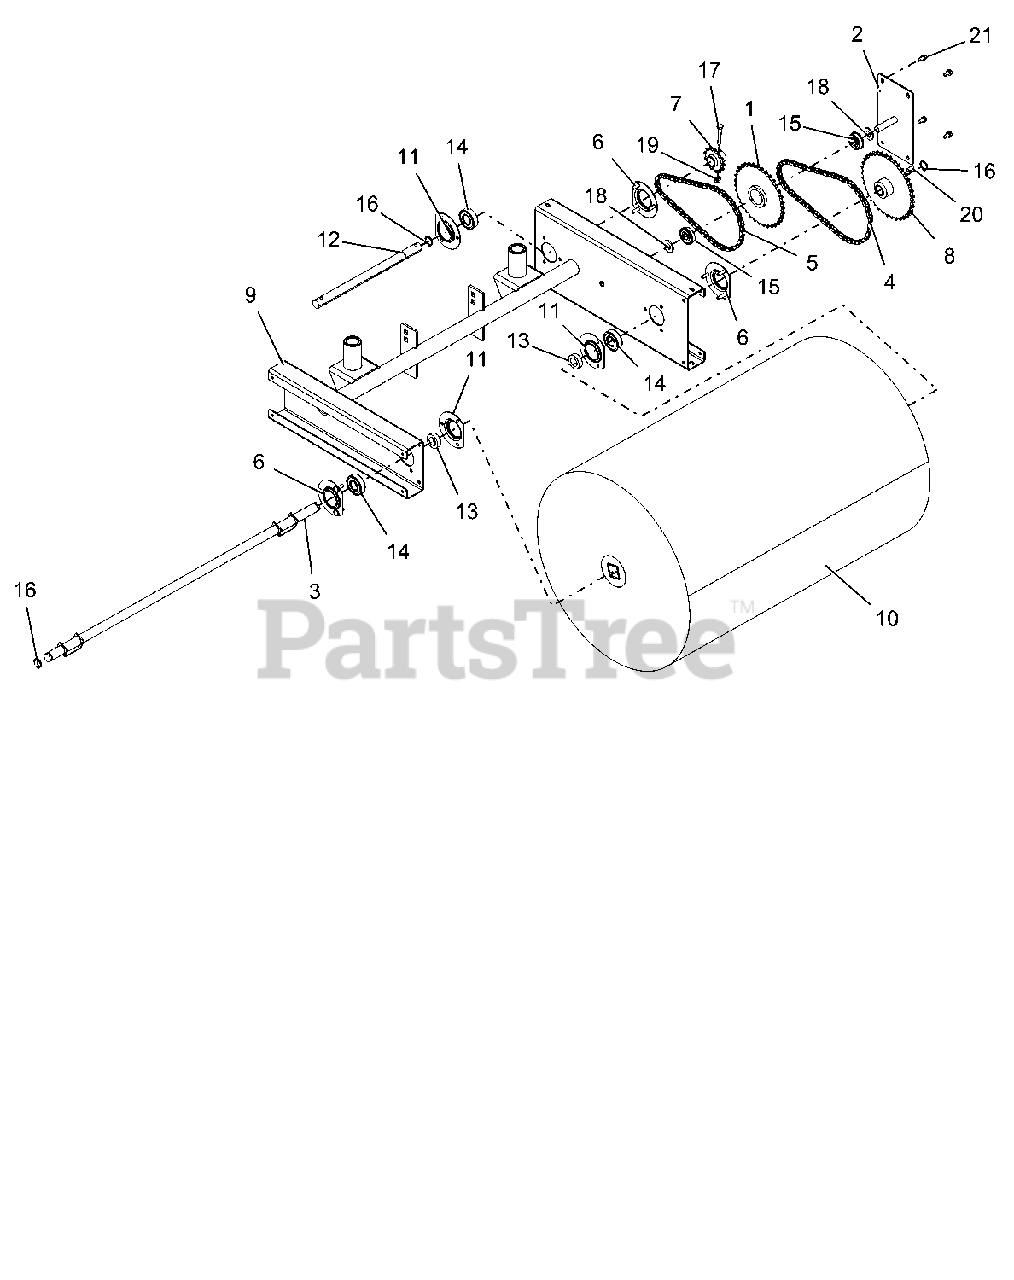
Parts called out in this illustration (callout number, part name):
1	SPROCKET, REDUCTION IDLER
2	MOUNT, REDUCTION IDLER
3	SHAFT, 28" BRUSH
4	CHAIN, #40-54 LINKS
5	CHAIN, #41-50 LINKS
6	BEARING FLANGE
7	SPROCKET, DRIVE
8	SPROCKET, DRIVEN
9	FRAME, POWER BROOM-DELUXE
10	BRUSH, 18"DIA X 28"WIDE
11	BEARING FLANGE
12	SHAFT, TRANSMISSION
13	SPACER .755X1.250X.370
14	BRG-BALL .750X1.750X.50
15	BRG-BALL .50X1.38X.438 SEALED
16	RG-RTNG-EXT .689X.078
17	BLT-HEX .25-20X1.75 GR5 YWZC
18	WSHR-FL-STL .536X1.07X.109 YZ
19	NUT-LK-TOP-FLG .25-20 YWZC
20	KEY-WDRF .188X.75X.313 SAE 9
21	SCR-TAP .25-20X.50 HWH TR YWZ
